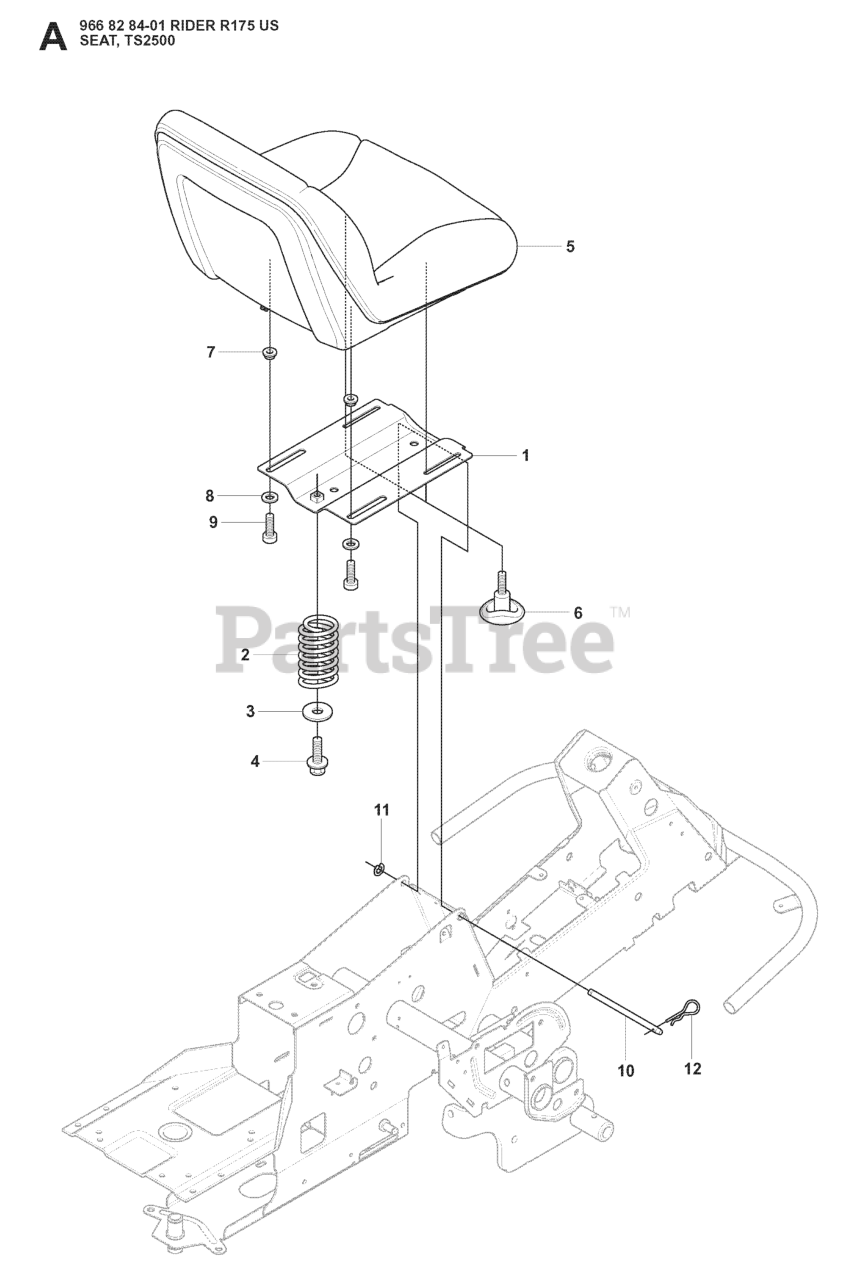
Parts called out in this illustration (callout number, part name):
1	SEAT BRACKET
2	SEAT SPRING
4	Screw M10x25
5	SEAT
6	ADJUSTING KNOB
11	RETAINING RING SGA 10
